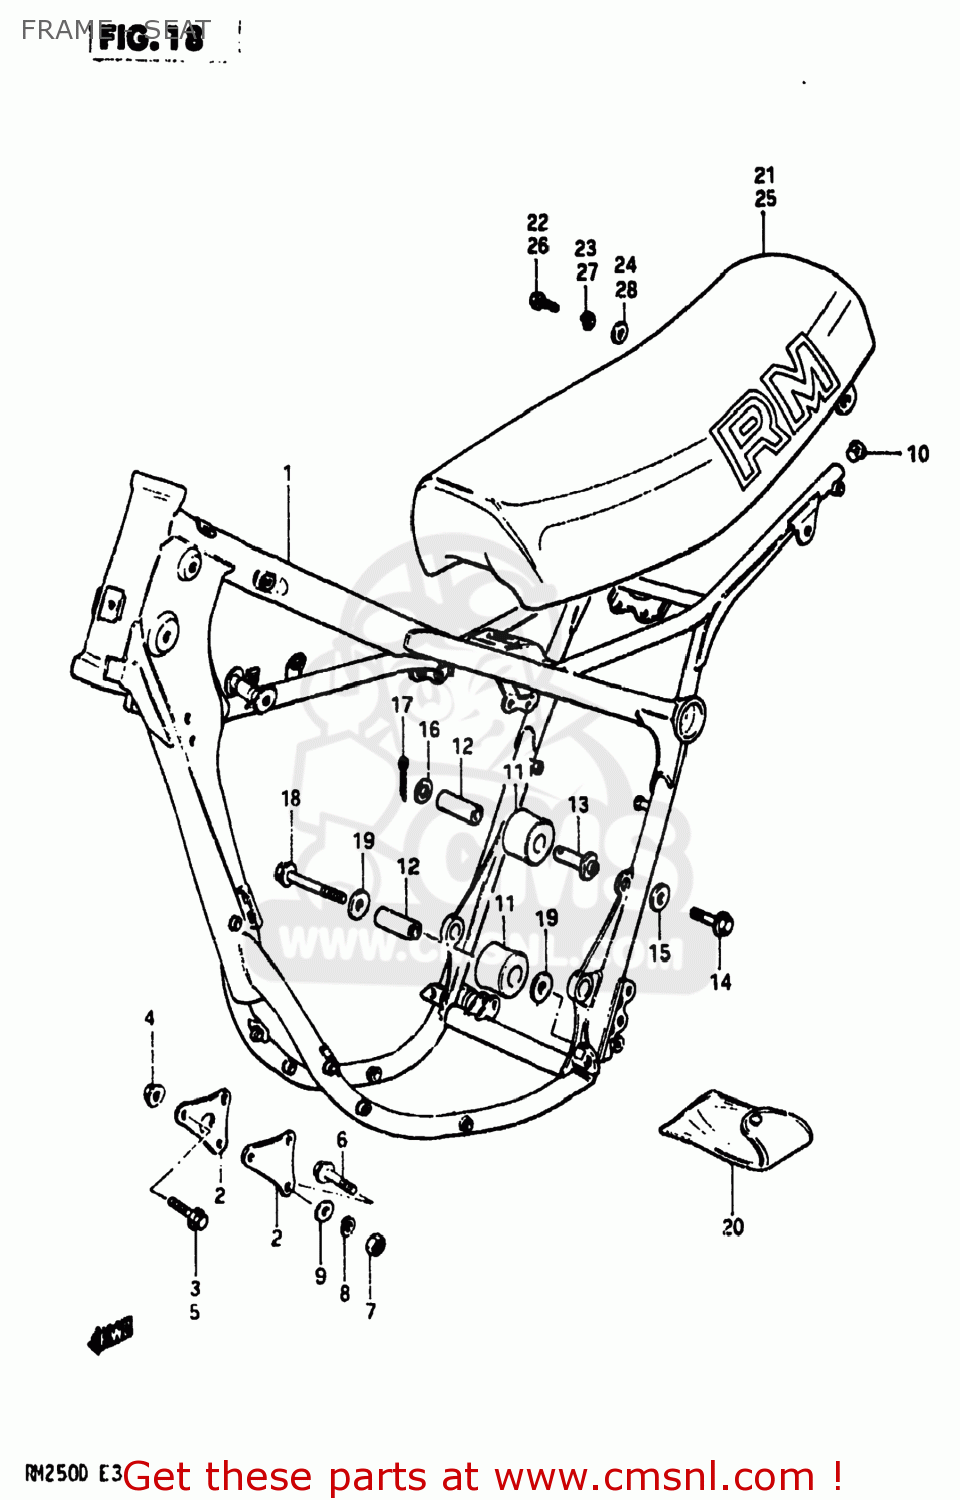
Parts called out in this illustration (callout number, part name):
1	FRAME
2	PLATE,ENGINE MOUNTING
3	BOLT 8X55
4	NUT
5	BOLT 8X55
6	BOLT
7	NUT 8MM
8	LOCK WASHER
9	WASHER
10	PLUG(OD:17)
11	ROLLER,CHAIN LENGTH CONTROL
12	SPACER,CHAIN LENGTH ROLLER
13	BOSS,CHAIN LENGTH ROLL
14	BOLT,REAR
15	WASHER
16	WASHER
17	PIN 25X20
18	BOLT(8X45)
19	WASHER
20	TOOL SET
21	SEAT ASSEMBLY
22	BOLT
23	WASHER,LOCK,8.
24	WASHER (8.5X20X2.6)
25	SEAT ASSEMBLY
26	BOLT
27	LOCK WASHER
28	WASHER
